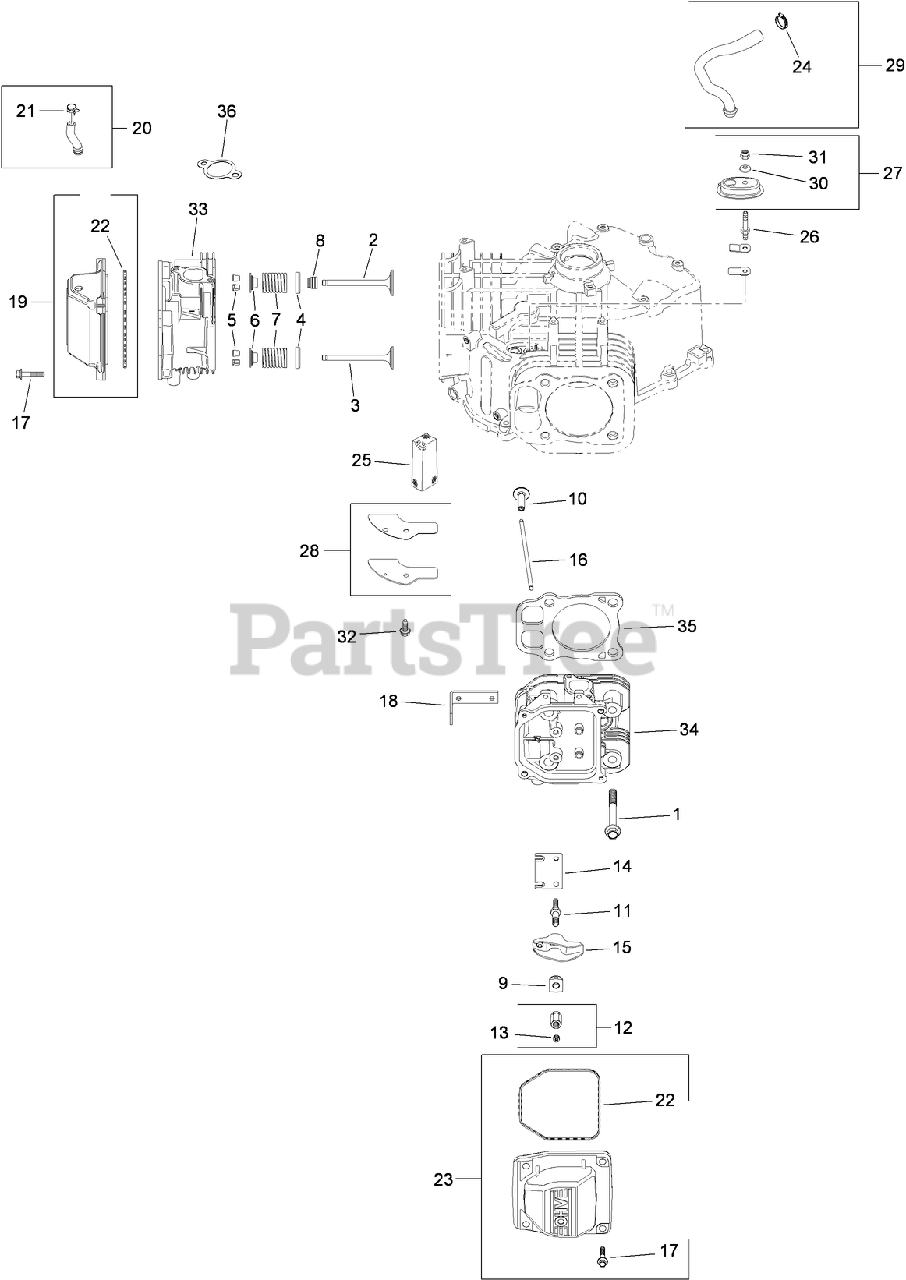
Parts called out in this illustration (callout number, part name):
1	SCREW-FLANGE (M10X1.5X90)
2	VALVE-INTAKE (STD)
3	VALVE-EXHAUST (STD)
4	RETAINER-SPRING
5	RETAINER KIT
6	CAP-SPRING, VALVE
7	SPRING-VALVE
8	SEAL-STEM, VALVE
9	PIVOT-ARM, ROCKER
10	TAPPET KIT
11	STUD-ROCKER
12	HEX NUT ASM (INCLUDES REF 32)
13	SCREW-SET
14	PLATE-GUIDE
15	ARM-ROCKER
16	ROD-PUSH
17	SCREW-FLANGE (M6X1.0X30)
18	STRAP-LIFTING
19	BREATHER VALVE COVER KIT
20	FUEL PUMP HOSE W/CLAMP KIT (INCLUDES REF 36)
21	CLAMP-HOSE
22	O-RING
23	PLAIN ROCKER COVER KIT
24	CLAMP-HOSE, SPRING (1/2)
25	FILTER-BREATHER
26	STUD-COVER, BREATHER
27	BREATHER HOUSING KIT (INCLUDES 15-16)
28	BREATHER COVER KIT
29	BREATHER HOSE KIT
30	WASHER-SEALING
31	NUT-LOCK (M5X.8)
32	SCREW-FLANGE, THREAD FORMING (M6X1.0X16)
33	CYLINDER HEAD NO.1 ASM
34	CYLINDER HEAD NO.2 ASM
35	CYLINDER HEAD GASKET KIT
36	GASKET-EXHAUST
